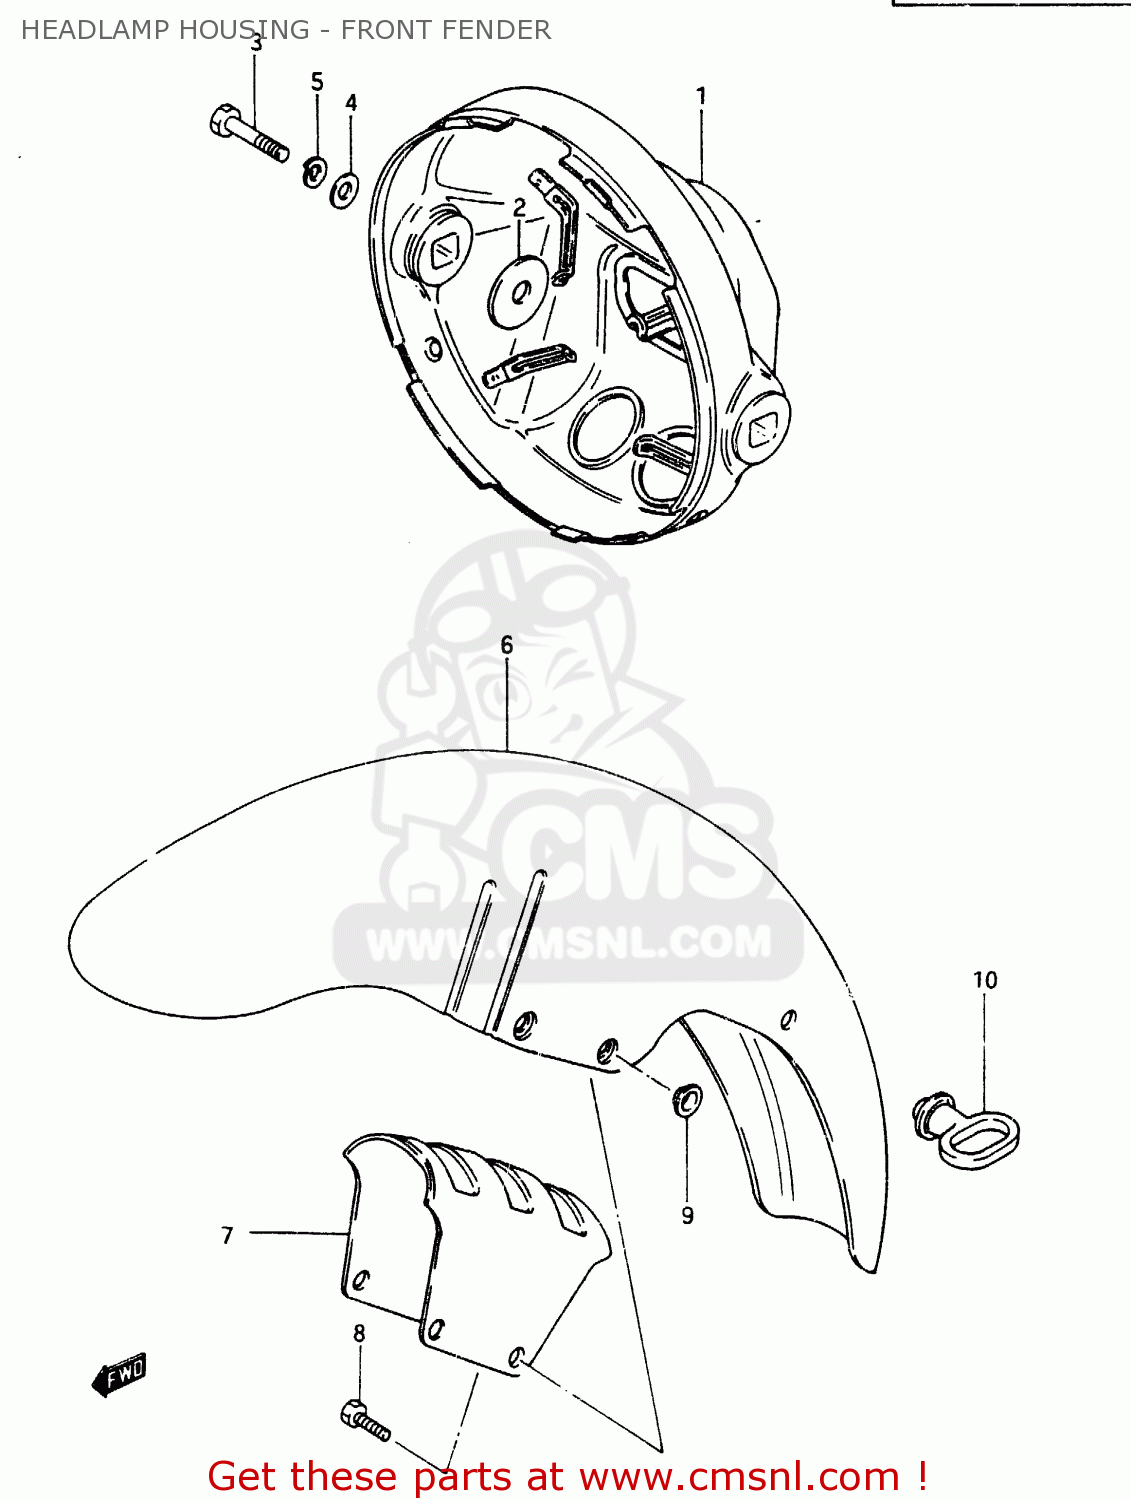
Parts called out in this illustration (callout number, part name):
1	HOUSING,HEADLAMP(BLACK)
2	WASHER (8.5X29X1.6)
3	BOLT
4	WASHER
5	LOCK WASHER
6	FENDER,FR
7	BRACE,FRONT FENDER
8	BOLT
9	WASHER
10	GUIDE,CABLE
